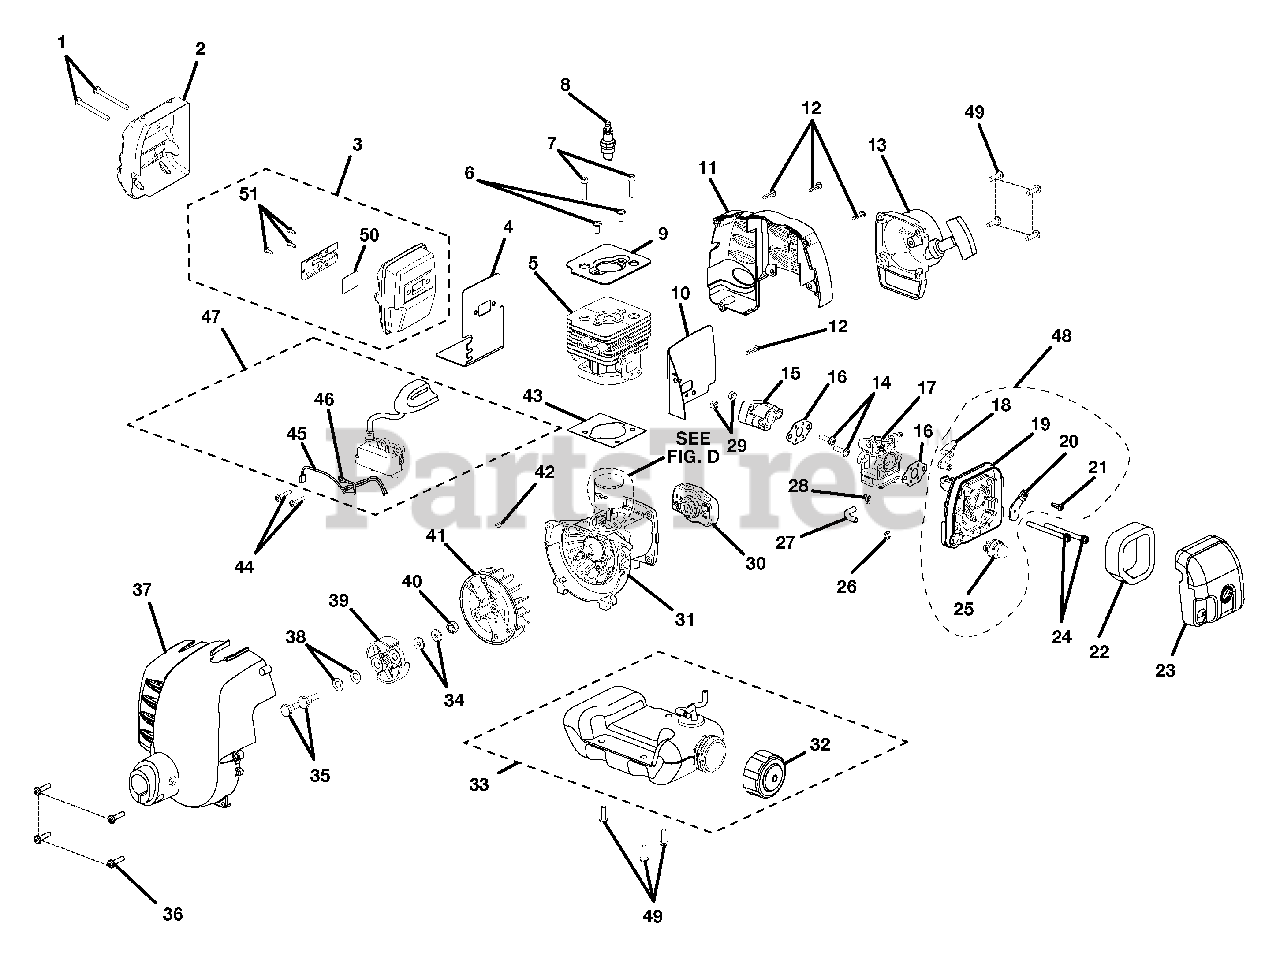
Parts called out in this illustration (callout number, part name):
1	SCREW (M5 X 50 mm TORX SLOTTED RECESSED PAN HD.)
2	HEAT SHIELD
3	MUFFLER ASSEMBLY
4	MUFFLER GASKET
5	CYLINDER
6	SCREW (M5 X 10 in. TORX RECESSED PAN HD.)
7	SCREW (M5 X 22 mm SOCKET HD.)
8	SPARK PLUG
9	CYLINDER PLATE
10	INSULATOR GASKET
11	ENGINE HOUSING, REAR
12	SCREW (M4 X 16 mm TORX RECESSED PAN HD.)
13	STARTER RECOIL ASSEMBLY
14	SCREW (M5 X 31 mm Torx SLOTTED RECESSED PAN HD.)
15	HEAT DAM INSULATOR
16	CARBURETOR GASKET
17	CARBURETOR ASSEMBLY
18	CHOKE LEVER
19	CARBURETOR PLATE
20	CHOKE PLATE
21	SCREW (M4 X 12 mm SLOTTED RECESSED PAN HD.)
22	ELEMENT
23	COVER ASSEMBLY
24	SCREW (M5 X 60 mm, SLOTTED RECESSED PAN HD. MACHINE)
25	PRIMER ASSEMBLY
26	HOSE CLIP
27	FUEL LINE
28	HOSE CLIP
29	NUT (M5 x .8 mm)
30	PULLEY ASSEMBLY
31	CRANKCASE ASSEMBLY
32	FUEL CAP ASSEMBLY
33	FUEL TANK ASSEMBLY
34	WASHER
35	CLUTCH SCREW
36	SCREW (M5 X 20 mm TORX SLOTTED RECESSED PAN HD.)
37	FRONT HOUSING ASSEMBLY
38	CURVED WASHER
39	CLUTCH ASSEMBLY
40	ROTOR NUT
41	ROTOR
42	WOODRUFF KEY (10 mm X 3 mm)
43	GASKET
44	SCREW (M4 X 22 mm TORX SLOTTED RECESSED PAN HD.)
45	LEAD ASSEMBLY, BLACK
46	LEAD ASSEMBLY, RED
47	COIL BOOT ASSEMBLY
48	FILTER HOUSING ASSEMBLY
49	SCREW (M5 X 16 MM TORX SLOTTED)
50	SCREEN
51	SCREW (RECESS PAN HD)
